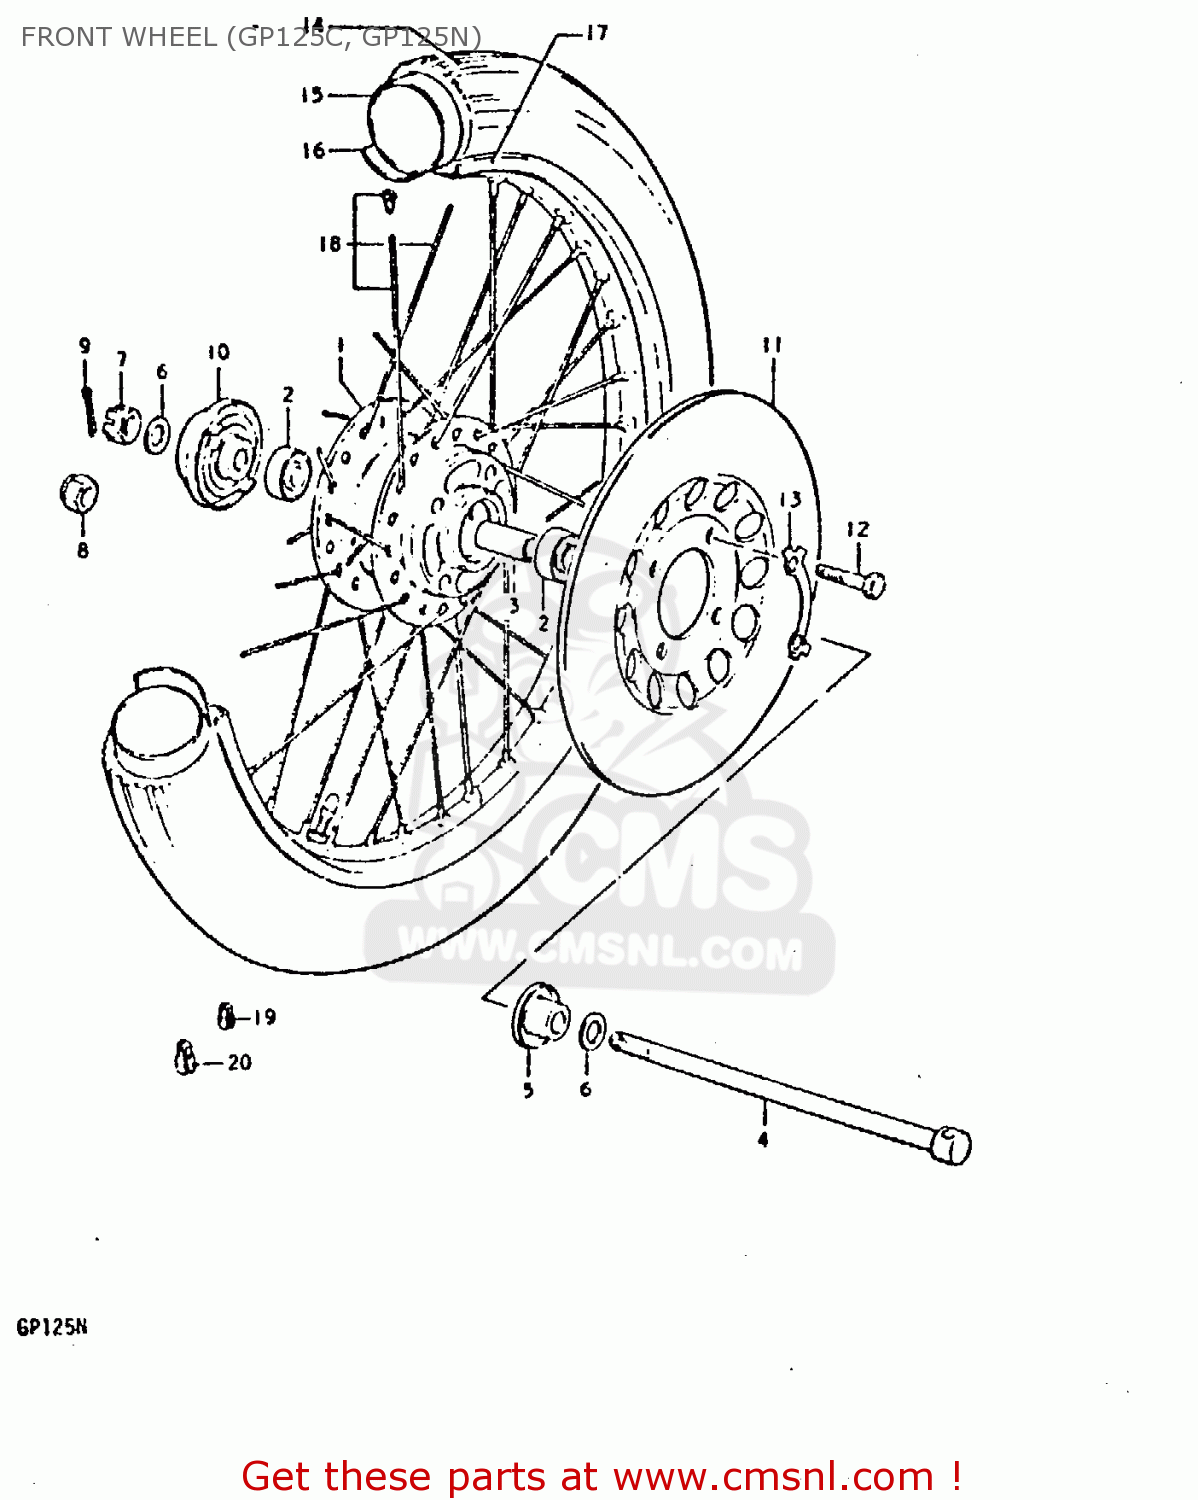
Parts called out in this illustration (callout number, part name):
1	HUB,FR
2	BEARING
3	SPACER (10.2X16X51)
4	AXLE,FRONT
5	SPACER,FR AXLE,L
6	WASHER
7	NUT
9	COTTER PIN
10	BOX ASSY,SPEEDOMETER GEAR
11	DISK, BRAKE
12	BOLT(8X30)
13	WASHER
14	TIRE,FRONT
15	TUBE,INNER
16	PROTECTOR,INNER TUBE
17	RIM,WHEEL
18	SPOKE SET,FRONT
19	BALANCER,WHEEL (B)
20	BALANCER,WHEEL (30G)
